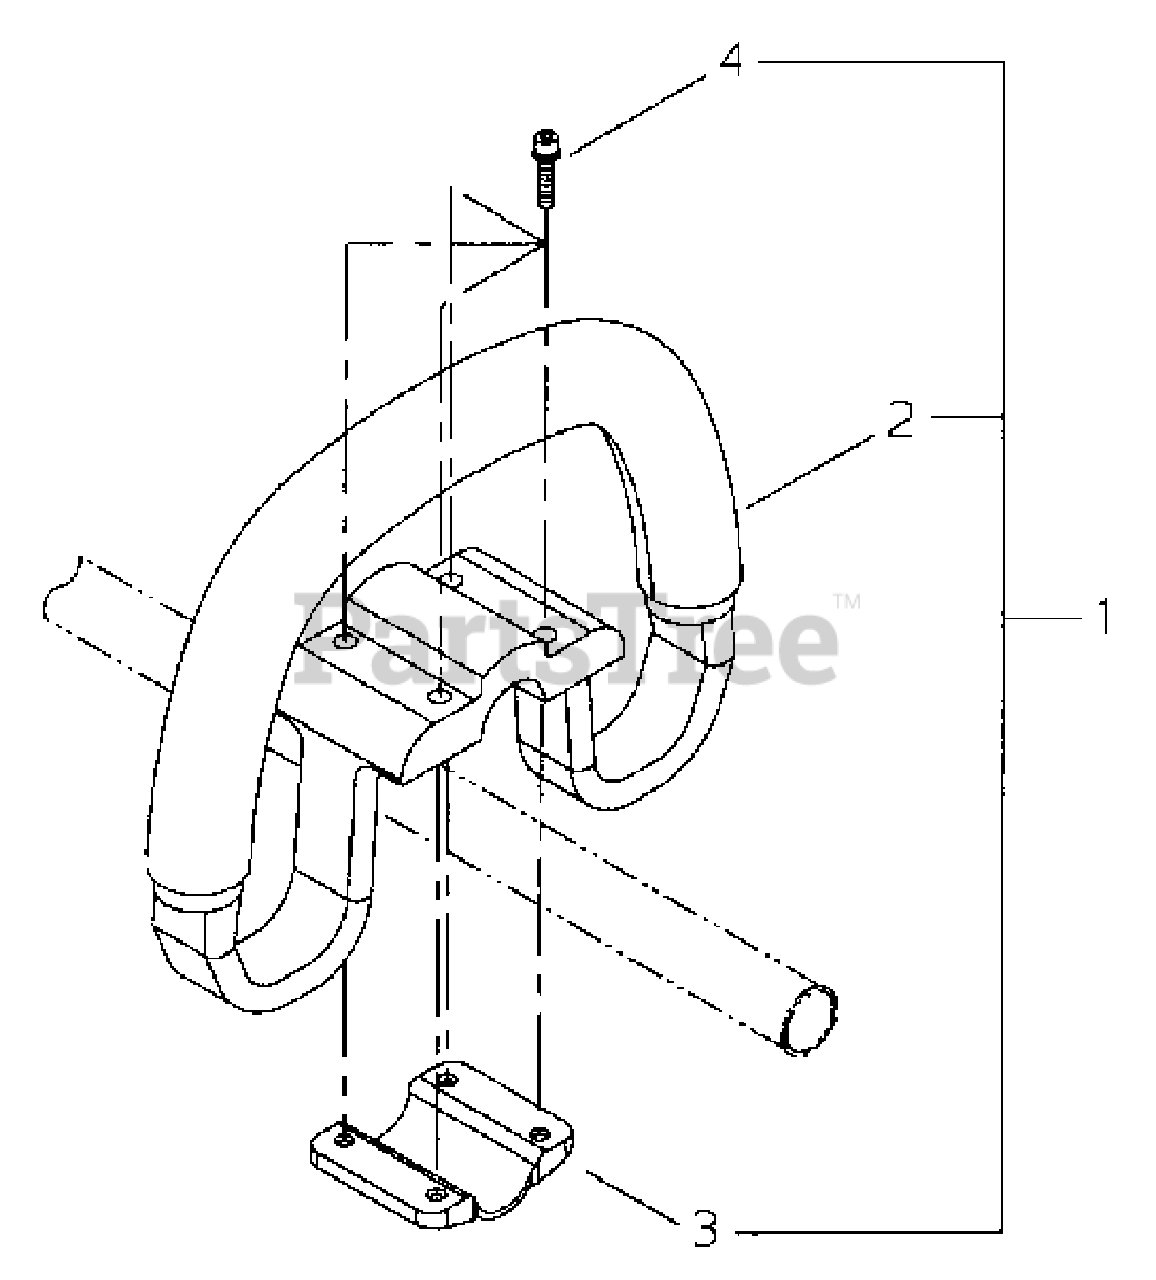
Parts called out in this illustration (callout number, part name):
1	HANDLE ASSY - SUPPORT
2	HANDLE
3	BRACKET, MOUNTING
4	BOLT M5×25
